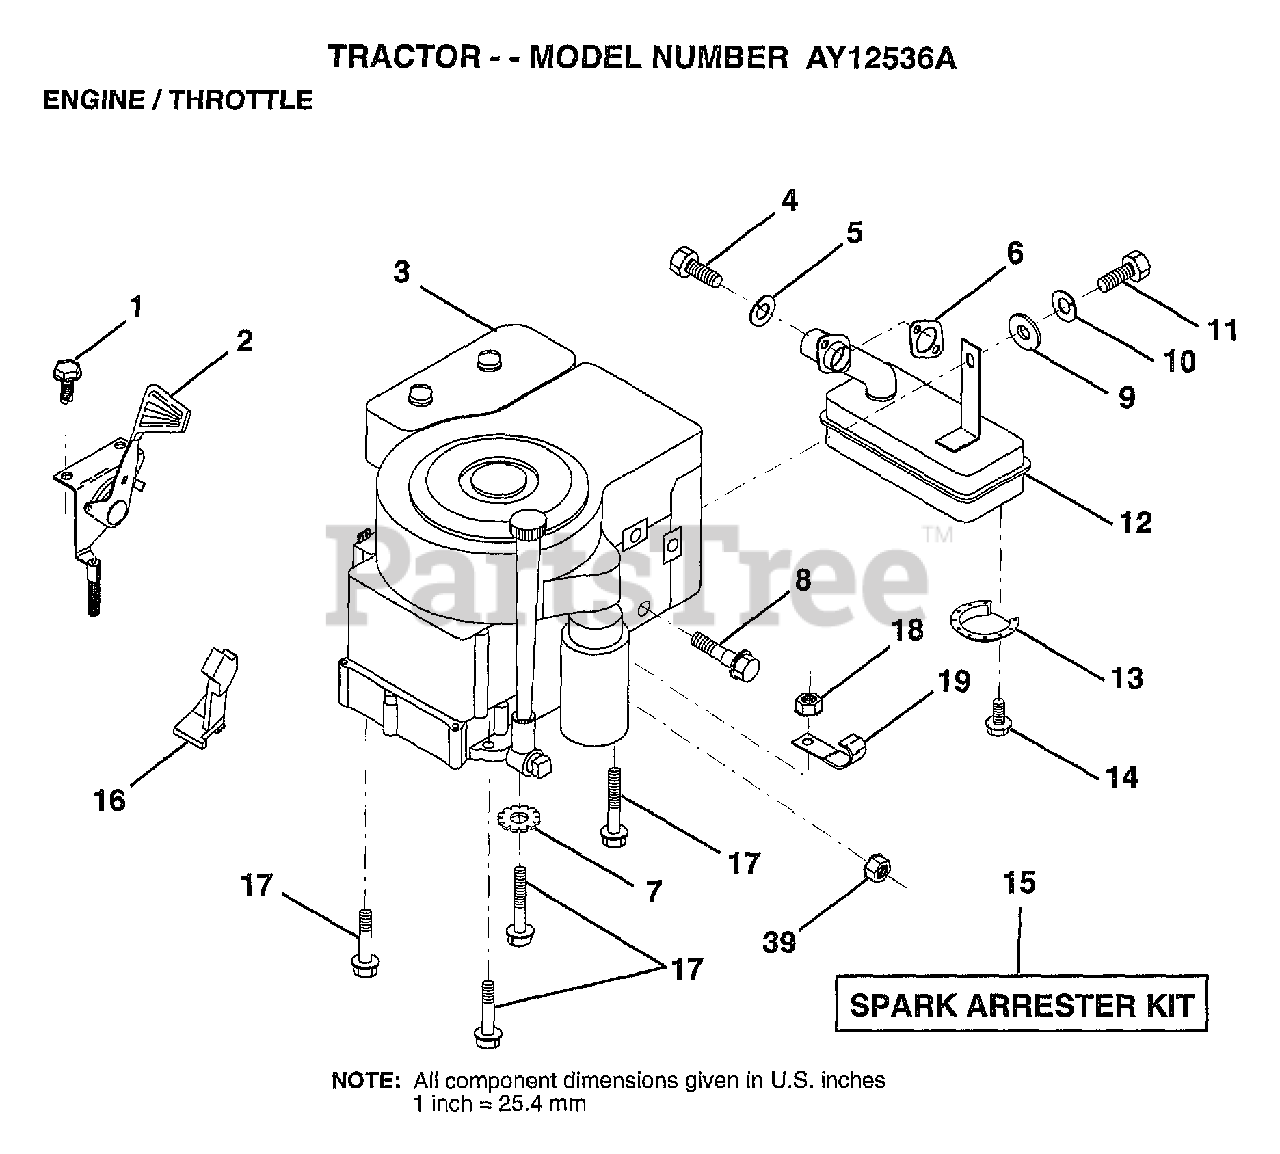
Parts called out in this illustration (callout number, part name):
1	SCREW.1/4-20X1/2
4	SCREW
5	LOCKWASHER
6	GASKET ENG 1 313 LD TIN PLATED
7	LOCKWASHER
8	BOLT T
10	LOCKWASHER
12	MUFFLER
13	DEFLECTOR.222573
16	"STOP,DASH THROTT"
17	SCREW LT
18	NUT
19	CLIP T
39	NUT
